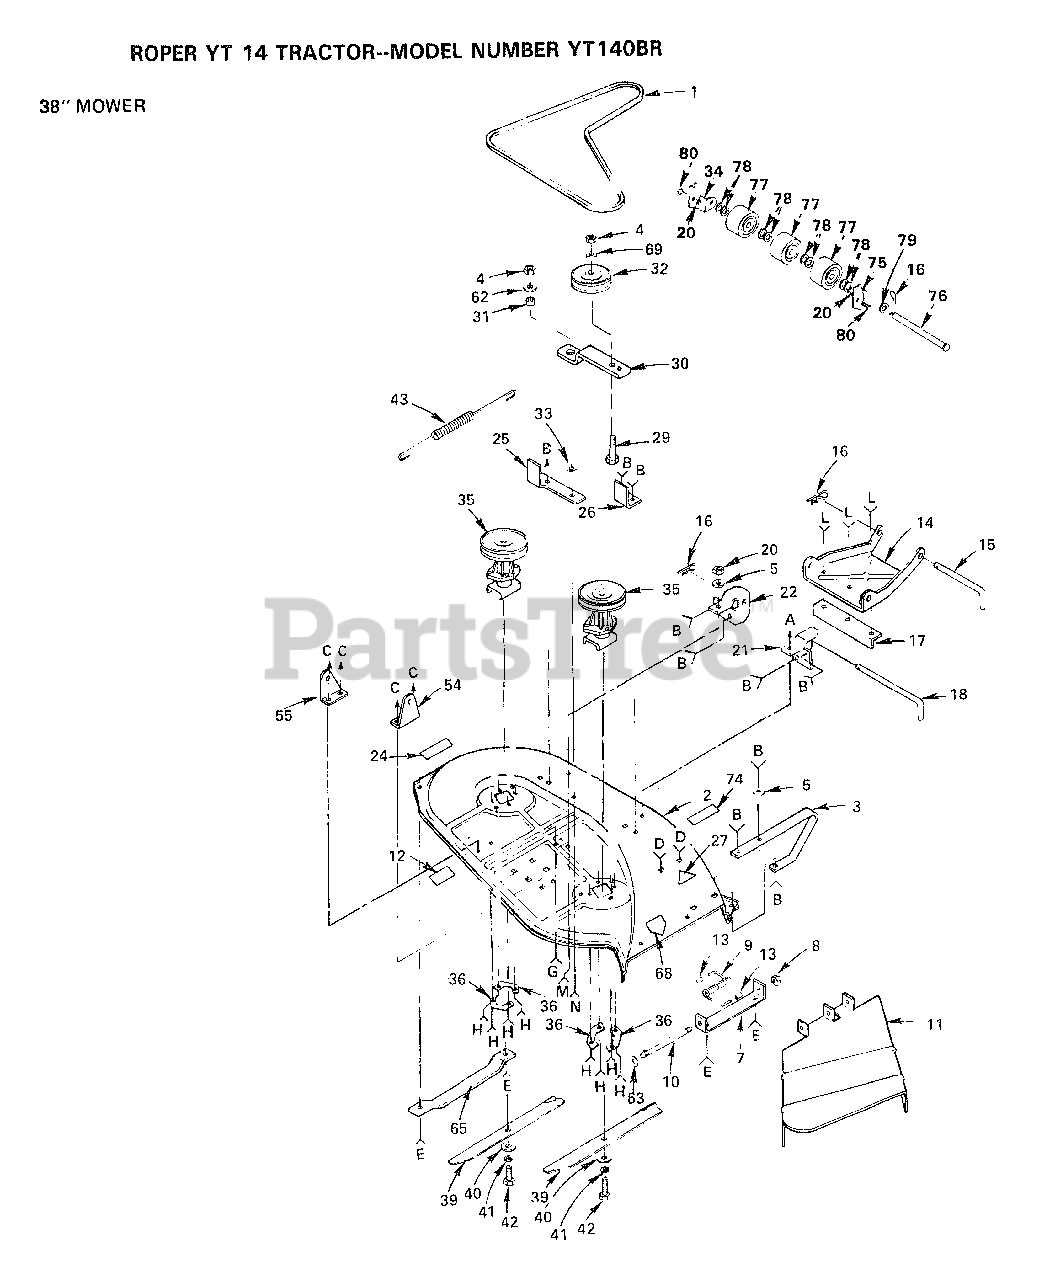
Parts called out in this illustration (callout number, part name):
1	BELT-V.79.1.MWR
5	WASHER M
10	ROD-HINGE T
11	DEFLECTOR-SHLD T
13	CAP-SLEEVE LT
14	LINK.PARALLEL
15	"ROD, FRT. PARAL T"
16	SPRING.RETAINER
17	LINK STOP
18	HINGE PIN T
21	BRACKET RH LT
22	BRACKET LH T
24	DECAL INSTRUCTION CAUTION
25	SUPPORT ARM T
26	STOP T
27	DECAL - SAFETY STANDARD
31	SPACER RETAINER
32	IDLER-FLAT T
33	"WASHER, WEAR LT"
34	BRACKET LH T
36	SUPPORT PLATE LT
40	WASHER
42	BOLT.3/8-24X1-1/2
43	"SPRING.EXT.8.5"""
54	"BRKT,SUSP RH T"
55	"BRKT,SUSP REAR LH"
63	WASHER
65	RUNNER-LH M
69	WASHER
74	DECAL.WARNING.T
75	BRACKET RH T
76	PIVOT PIN T
77	ROLLER T
78	WASHER T
80	BOLT
